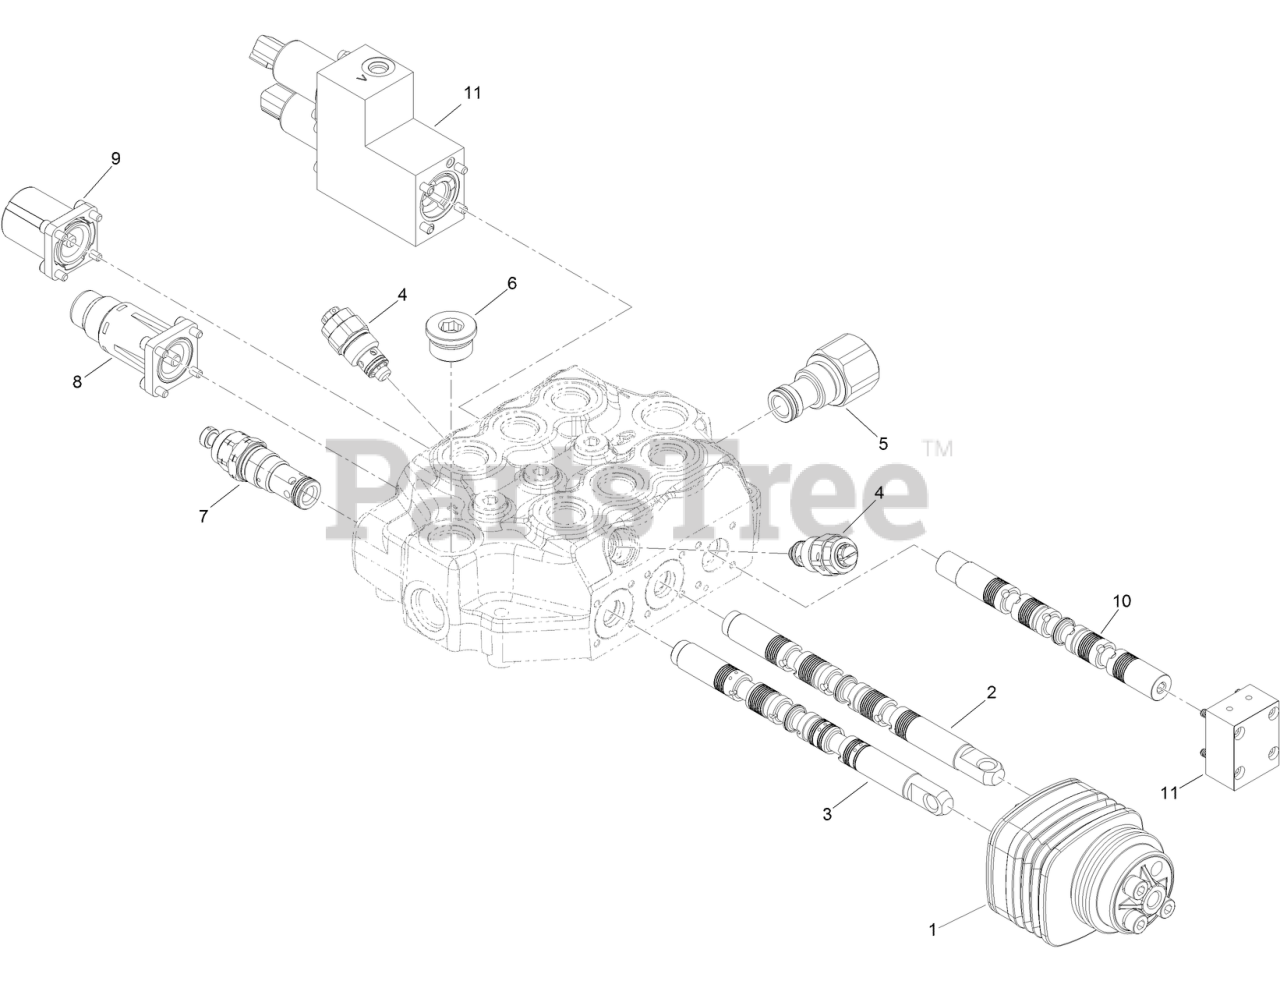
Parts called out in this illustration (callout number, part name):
1	KIT-COVER
2	VALVE-SPOOL
3	VALVE-SPOOL
4	CARTRIDGE-RELIEF
5	JOINT-SAE12
6	PLUG-SAE12
7	KIT-VALVE
8	KIT-COMMAND
9	KIT-CONTROL
10	VALVE-SPOOL
11	COMMAND KIT
